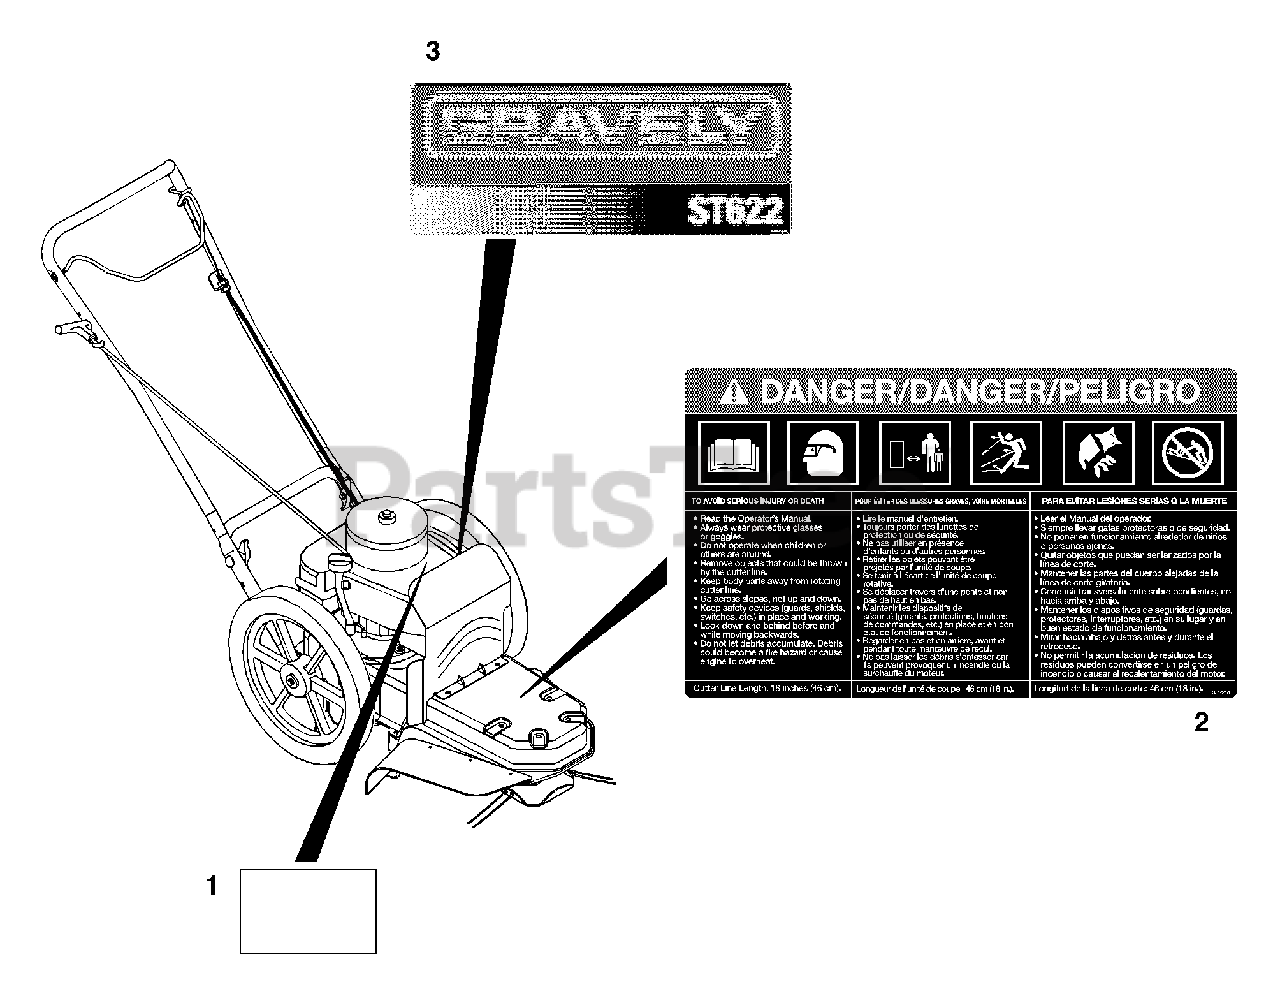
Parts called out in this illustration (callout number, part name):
1	Decal-6 H.P.-Gravely/Tecumseh
2	Decal-Danger
3	Decal-Gravely ST 622
